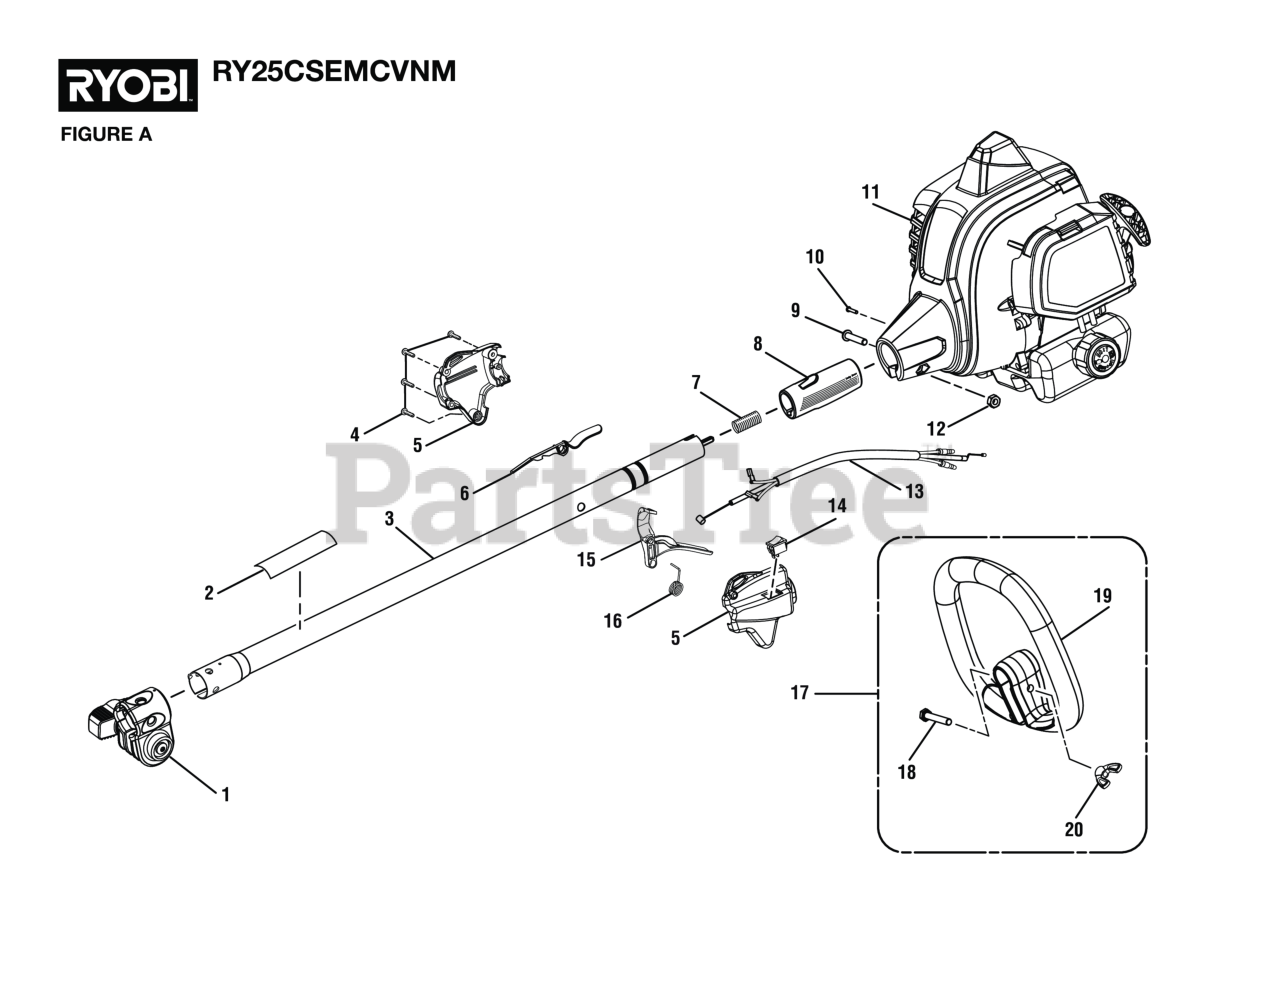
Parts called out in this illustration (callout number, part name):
1	Boom Clamp Assembly
2	Warning Icon Label
3	Upper Boom Assembly (Inc. Key Nos. 1-2)
4	Screw (M4 x 20 mm, T20 Torx Pan Hd. S.T.)
5	Control Handle Assembly (Inc. Key No. 6)
6	Trigger Lock
7	COMPRESSION SPRING
8	Rear Handle Grip
9	Screw (M6 x 30 mm, T27 Torx Button Hd.)
10	Screw (M4 x 8 mm, T25 Torx Pan Hd. T.F.)
11	Powerhead Assembly
12	Hex Nut (M6.3 x 1)
13	Throttle Cable and Wire Assembly
14	Stop Switch (Momentary Contact)
16	Torsion Spring (Throttle Trigger)
17	Auxiliary Handle Assembly
18	Screw (1/4-20 x 40 mm, Cap Hex Hd.)
19	Front Handle
20	Wing Nut (1/4-20, Plastic)
